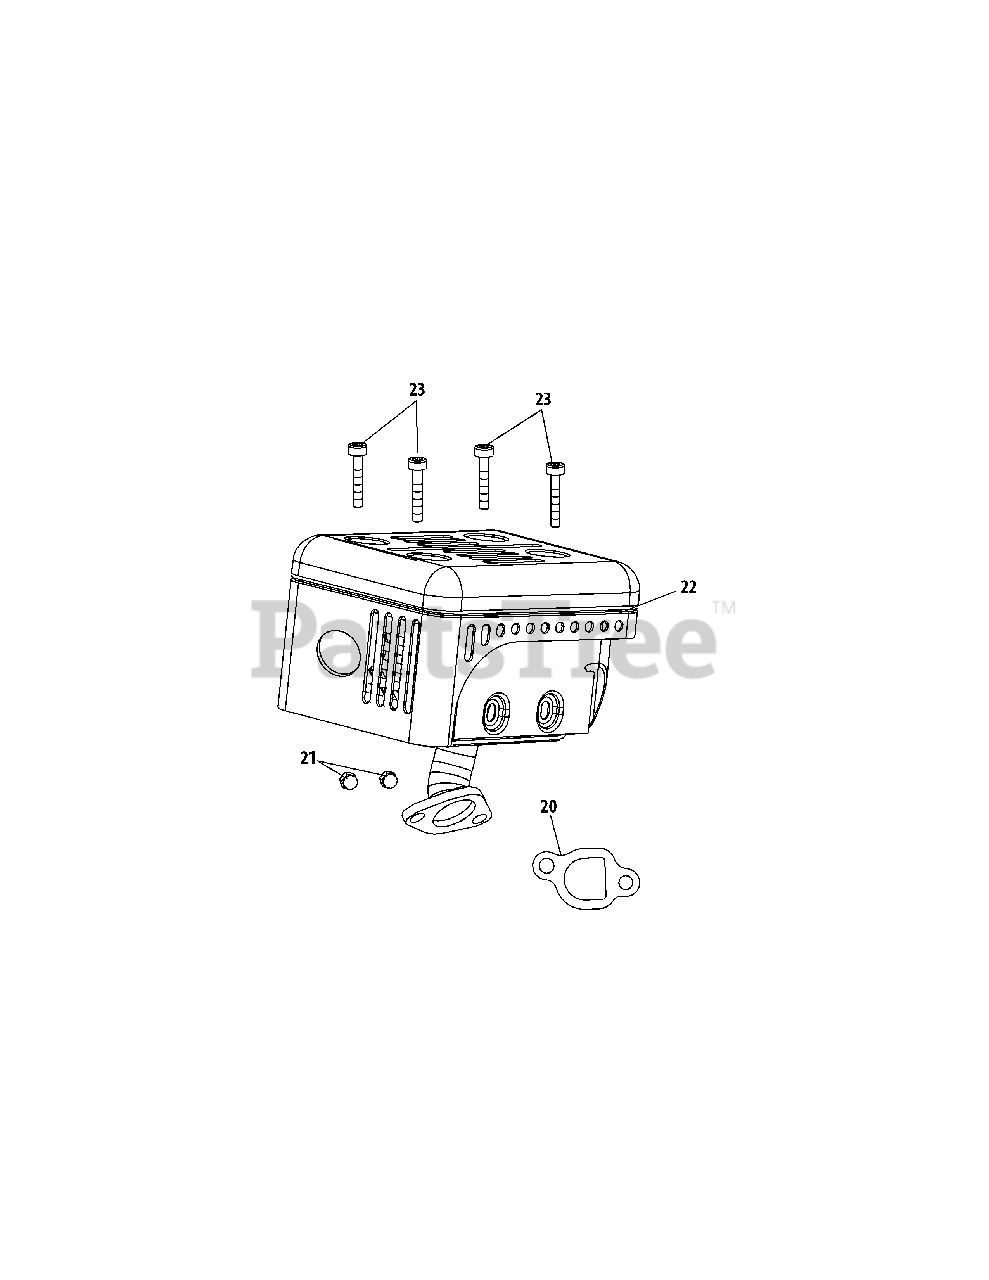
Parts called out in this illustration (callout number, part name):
20	Exhaust Pipe Gasket
22	Muffler Assembly
23	Bolt M5×10
